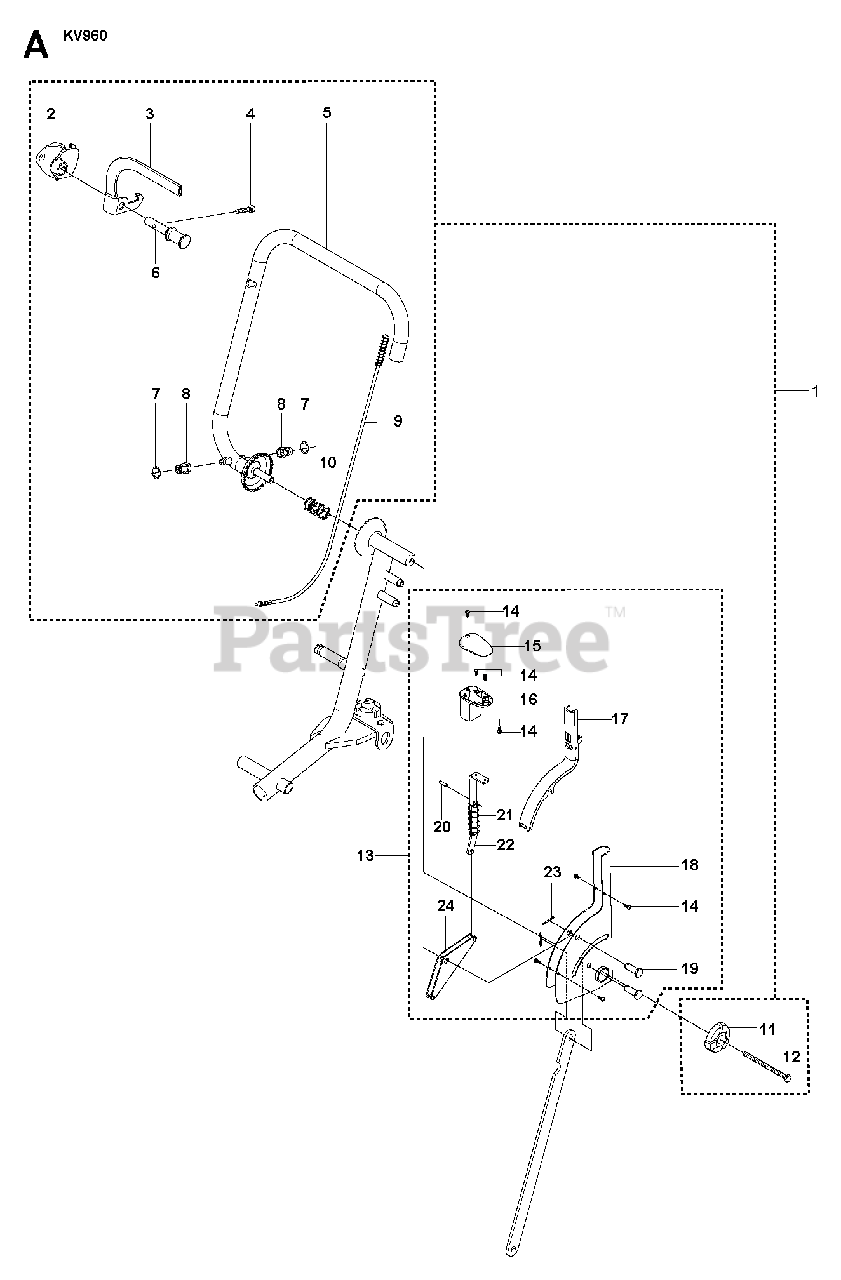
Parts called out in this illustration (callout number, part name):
1	HANDLEBAR ASSYIncl. 2 - 14
3	THROTTLE HANDLE ASSY
10	SPRING THROTTLE CONTROL
11	TURNING KNOB
14	SCREW CRPANT
